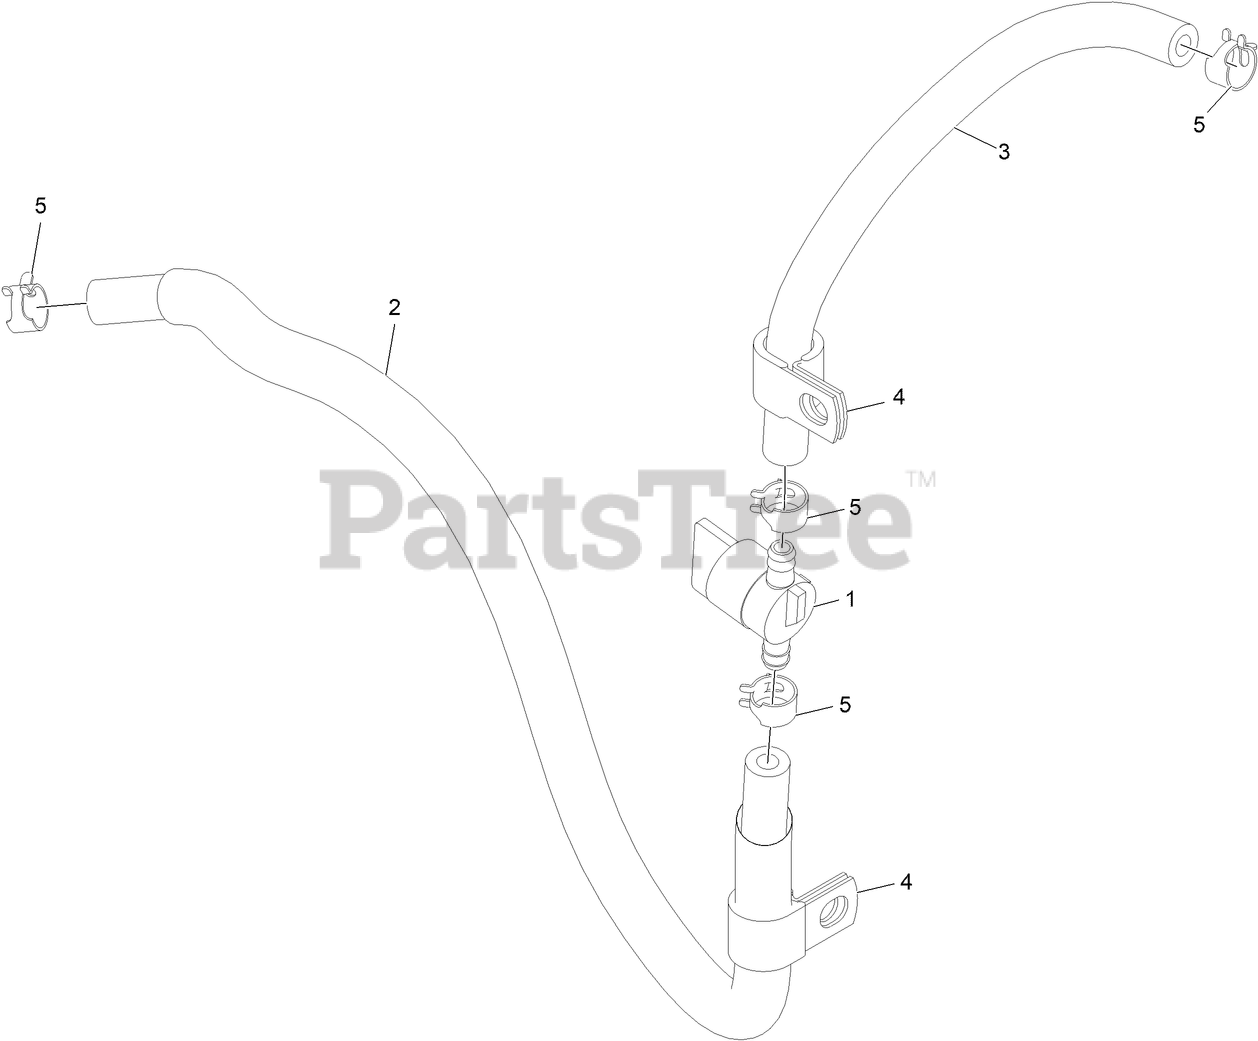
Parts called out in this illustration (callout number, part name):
1	VALVE-FUEL
2	HOSE-FUEL
3	HOSE-FUEL
4	CLAMP-R
5	CLAMP-HOSE
